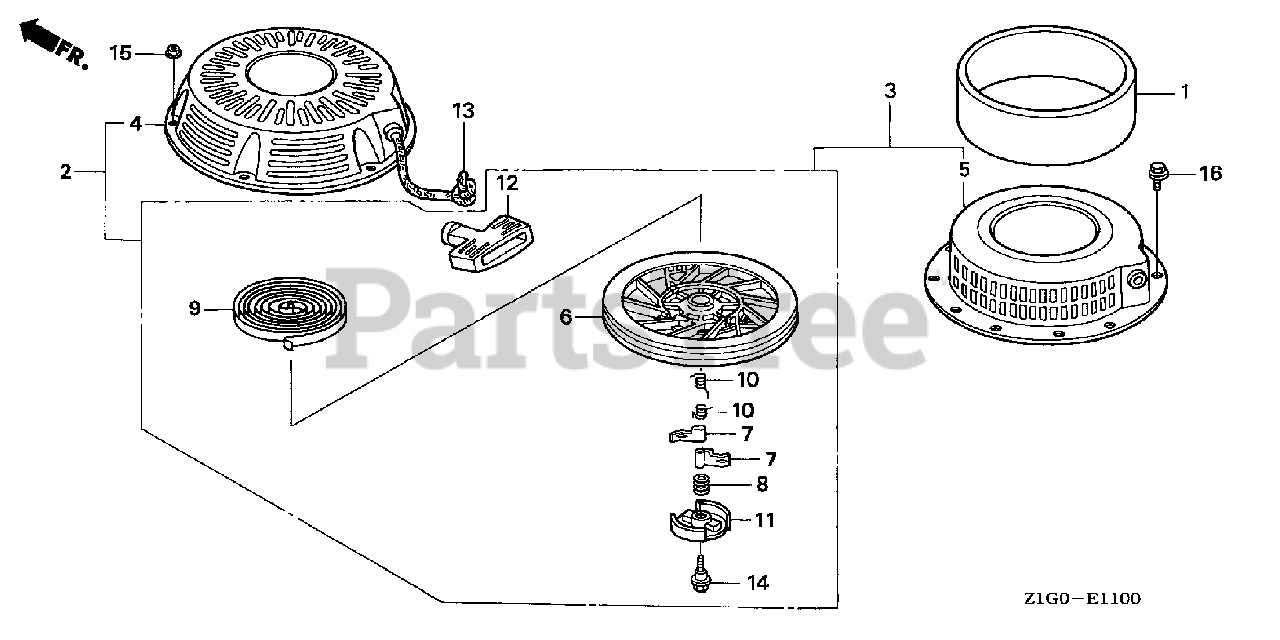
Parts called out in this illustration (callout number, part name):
1	FILTER, AIR
3	STARTER ASSY., RECOIL *R280* (POWER RED)
5	CASE, RECOIL STARTER *R280* (POWER RED)
6	PULLEY, RECOIL STARTER
7	RATCHET, STARTER
8	SPRING, FRICTION
9	SPRING, STARTER RETURN
10	SPRING, RATCHET
11	RETAINER, SPRING
12	GRIP, STARTER
13	ROPE, RECOIL STARTER
14	SCREW, CENTER
16	BOLT, FLANGE (6X10)
